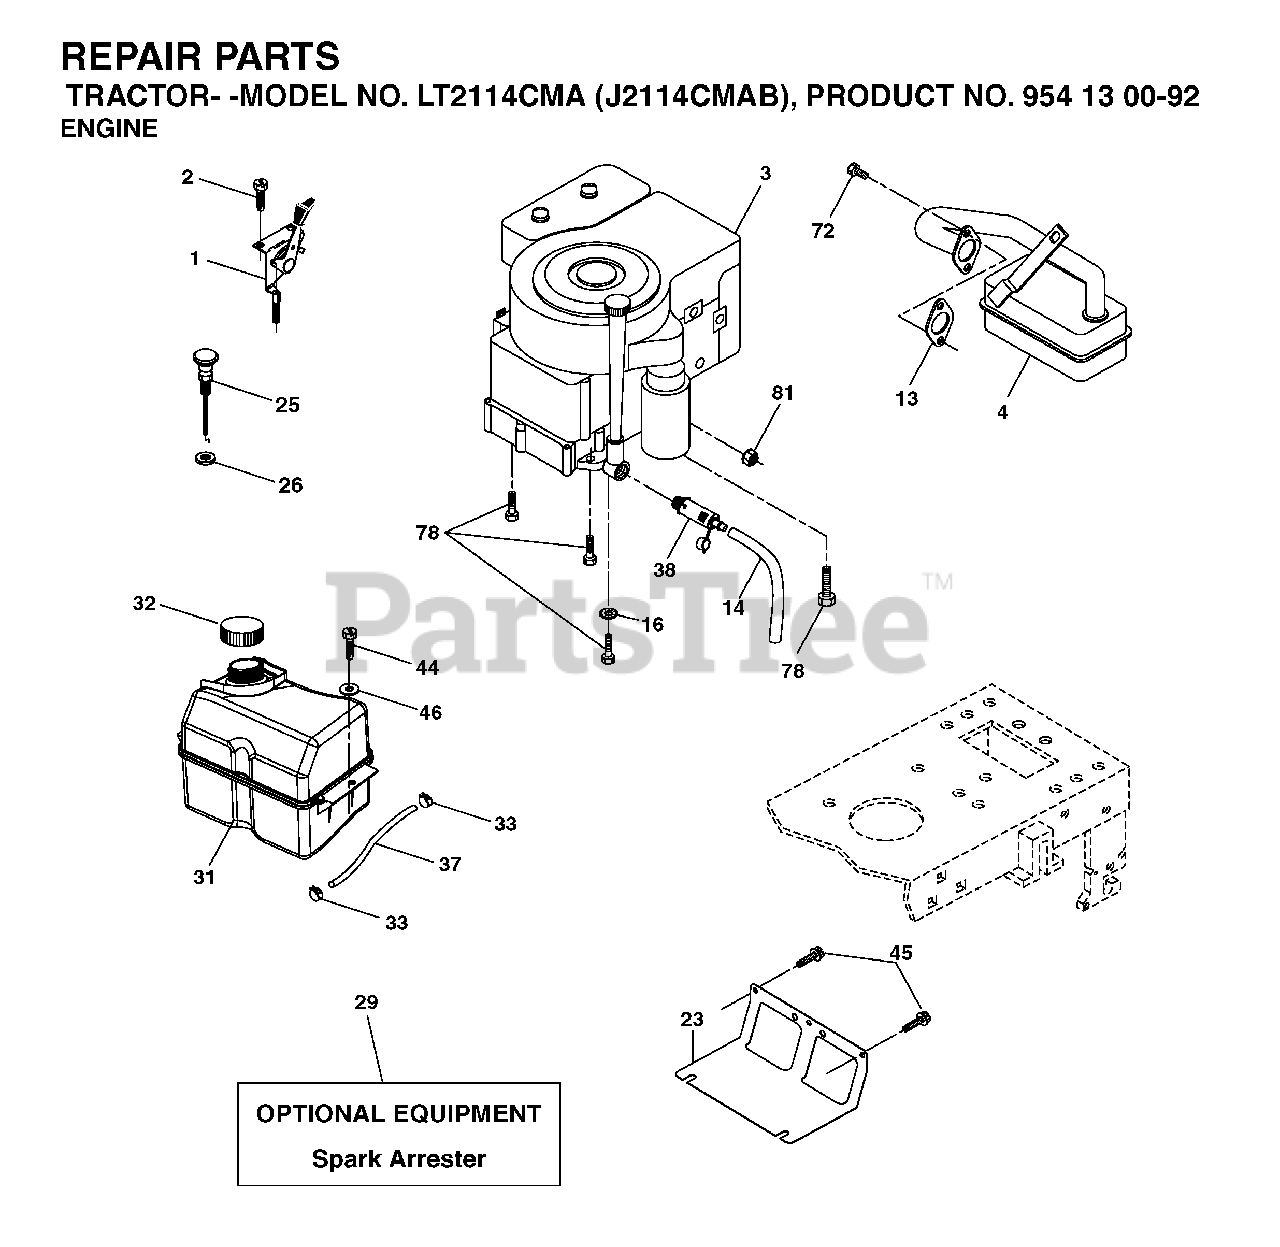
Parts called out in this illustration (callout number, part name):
1	CONTROL TH/CH FLAG
2	SCREW
13	REPL BY 532 27 22-93
14	TUBE, DRAIN OIL ASM.
16	LOCKWASHER
23	SHEILD.BROWNING.DBR.GUARD
26	NUT KEPS 3/8 - 24 UNF
29	ARRESTER SPARK (OPTIONAL)
31	TANK FUEL
32	FUEL CAP
33	HOSE CLAMP
37	LINE.FUEL.20
38	PLUG DRAIN OIL EASY
44	SCREW HEXWSHR 1/4-20X3/4
45	SCREW, 3/8-16X3/4
72	SCREW.SOCKET.HEAD.5/16-18
78	SCREW.3/8-16
81	NUT
